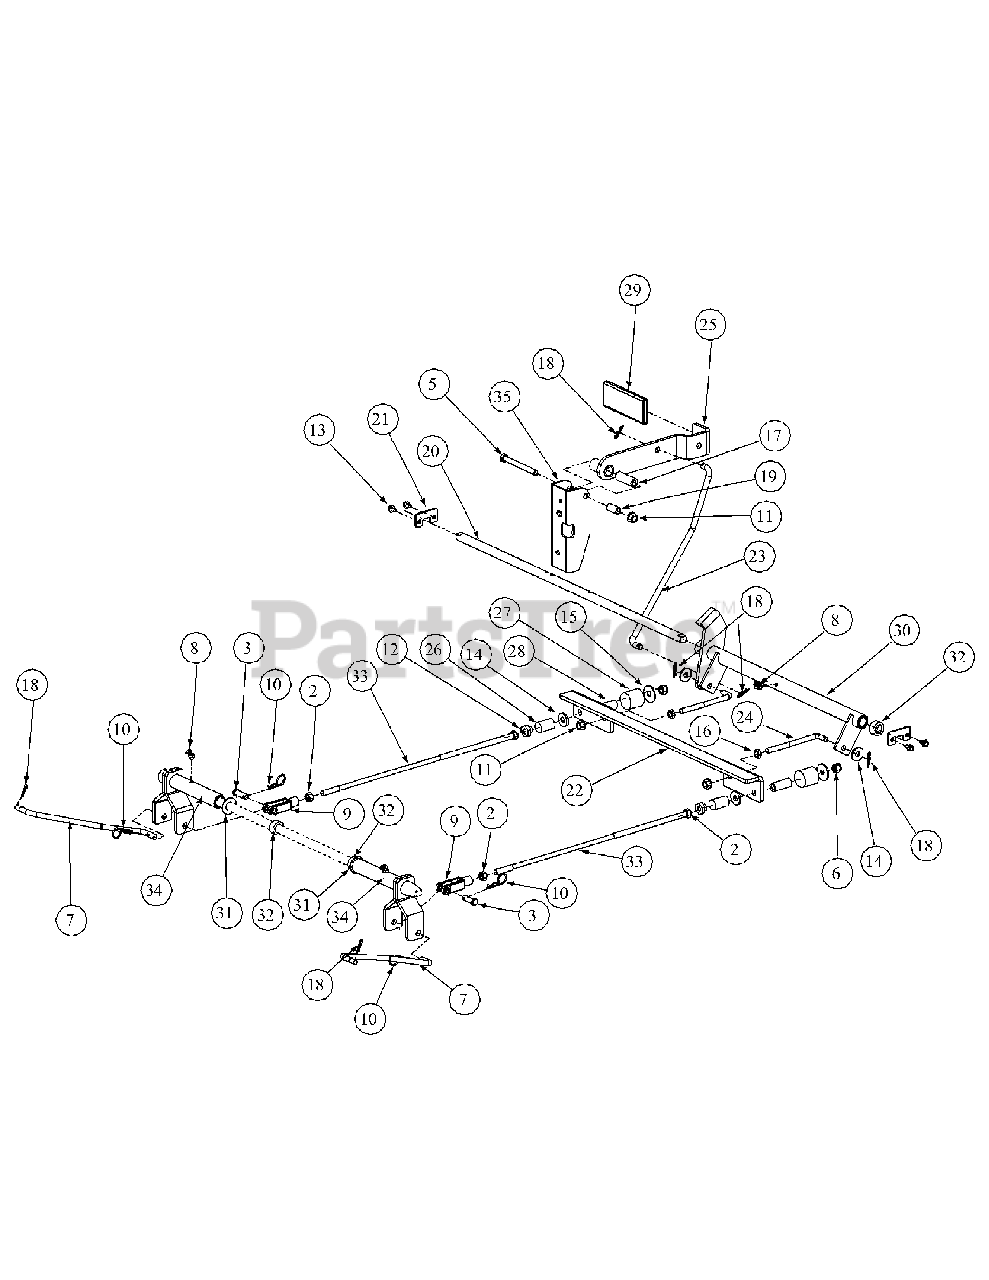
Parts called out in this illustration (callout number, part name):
2	Hex Nut, 3/8-16
3	Clevis Pin, 3/8 x 1-1/8
5	Hex Cap Screw, 3/8-16 x 3-1/2
6	Nylock Nut, 3/8-16
7	Linkage Brake Rod
8	Grease Fitting, 1/4 -28, 90 degree
9	Yoke, 3/8-16
10	Hair Pin, 3/8" - 1/2"
11	Flange Lock Hex Nut, 3/8-16
12	Shoulder Nut
13	Screw, 1/4-20 x 1-1/2
14	Flat Washer, .406 ID x 1.0 OD x .105
15	Flat Washer, .411 x 1.25 x .100
16	Jam Nut, 3/8-16
17	Spacer, .375 x .50 x 1.75
18	Cotter Pin, .072 x 1.12 Lg
19	Spacer, .375 x .50 x 1.02 Lg
20	Bellecrank Mounting Shaft
21	Parking Brake Shaft Holder
22	Brake Bracket
23	Brake Rod
24	Connector Rod, 3/8 OD x 5.75
25	Brake Handle
26	Neutral Brake Spring
27	Force Brake Spring
28	Center Brake Hose
29	Parking Brake Grip
30	Brake Bearing Hub
31	Flat Washer, 5/8
32	Shaft Collar, .625 ID x 1" OD x .438
33	Connector Rod, 3/8 OD x 17.88 Lg
34	Rear Brake Arm Assembly
35	Parking Brake Mounting Bracket
